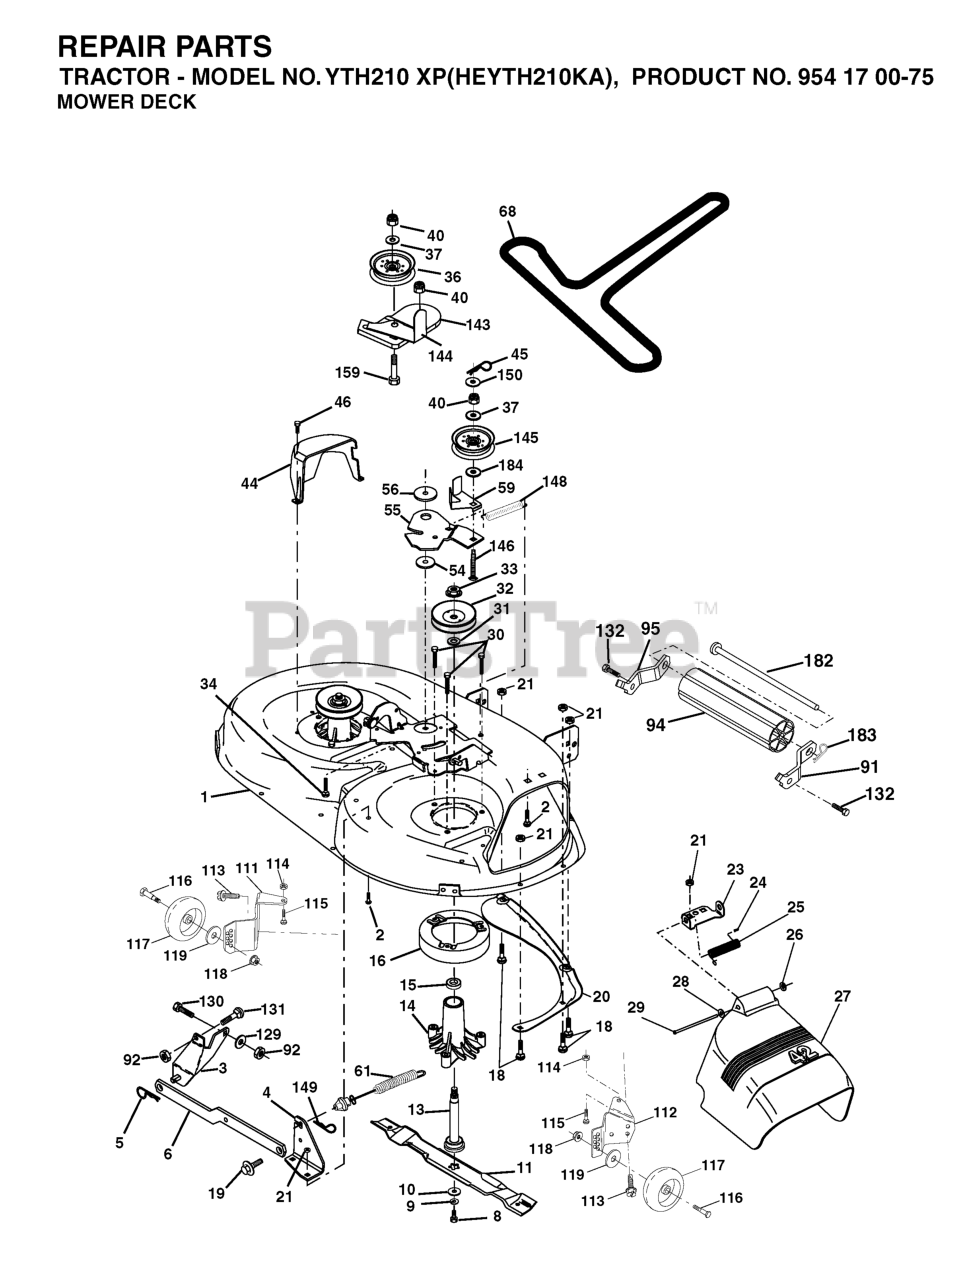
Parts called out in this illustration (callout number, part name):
1	42" DECK KIT
2	RP BOLT 5/16-18 X3/4 ZN/YEL GR
3	BRKT ASM SWAY BAR
4	BRACKET SWAY BAR 42" DECK
5	RETAINER-SPRNG RB
6	BAR SWAY DECK
8	BLADE BOLT
9	LOCKWASHER
10	WASHER.BLADE
11	Blade Mower 42" High Perf.
13	SHAFT ASM VENT
14	HOUSING.MANDREL.VENTED (MACHD)
16	STRIPPER.MANDREL.ROUND.BLACK
18	BOLT
19	BOLT SHD 5/16-18
20	BAFFLE.VORTEX
21	LOCKNUT
23	BRKT, DEFL. MOWER
24	CAP-SLEEVE LT
25	SPRING TORSION
26	NUT PUSH M
27	SHIELD DEFLECTOR
28	Washer 11/32 x 5/8 x 16 Ga SD
29	ROD.HINGE
30	SCREW, WASHER HEAD
31	WASHER
32	PULLEY/MANDREL
33	NUT, FLG TOPLOCK 9/16"
36	FLAT IDLER PULLEY
37	WASHER
44	GUARD MANDREL LH BLACK
45	RETAINER M
46	SCREW.1/4-20X5/8
55	ARM IDLER 42" MOWER LT/YT
56	SPACER.RETAINER.MOWER
59	GUARD, BELT
61	SPRING EXT ELEC CLUTCH
91	BRACKET ASM NOSEROLLER LH
92	NUT
94	NOSE ROLLER
95	BRACKET ASM NOSEROLLER RH
111	BRACKET, WHEEL
112	BRACKET, WHEEL
113	Screw Tapping 3/8-16 x .625
114	NUT
115	BOLT.CARR.5/16-18X5/8.SHORT
116	BOLT M
117	WHEEL.GAUGE.STANDARD
118	LOCKNUT
119	WASHER.5/16.FLAT.STE.STD.
129	WASHER
131	BOLT D
132	SCREW, 3/8-16X3/4
143	BRACKET, ARM IDLER
144	DNO KEEPER.BELT.42".CLUTCH.CBL
145	PULLEY
146	BOLT, CARRIAGE IDLER BLACK
148	IDLER RETURN SPRING
149	SPRING.RETAINER.YELLOW.ZINC
182	ROD ROLLER NOSE STANDARD
183	SPRING RETAINER
184	WASHER
